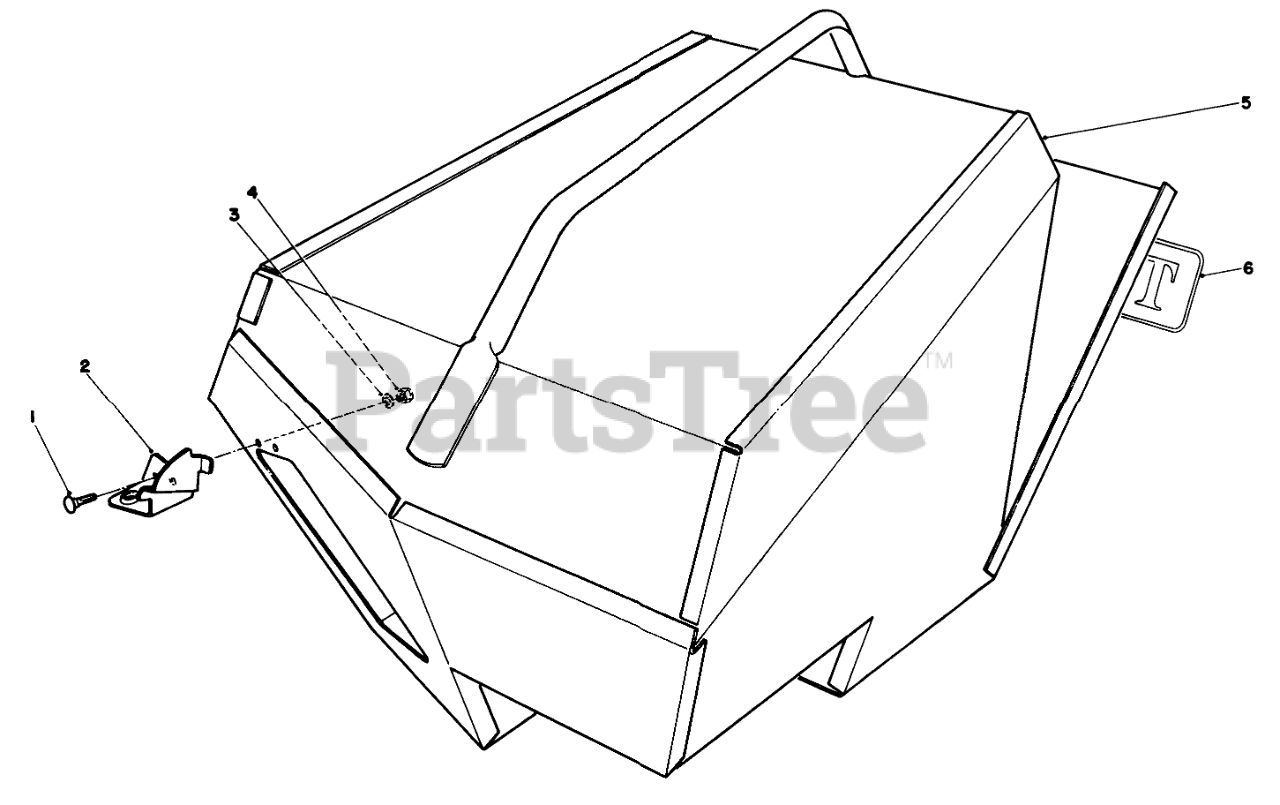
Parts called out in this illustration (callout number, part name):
1	SCREW-CARR
2	Bracket-Latch
3	WASHER-FLAT
4	NUT-LOCK, NI
5	Bag-Steel
6	Decal
